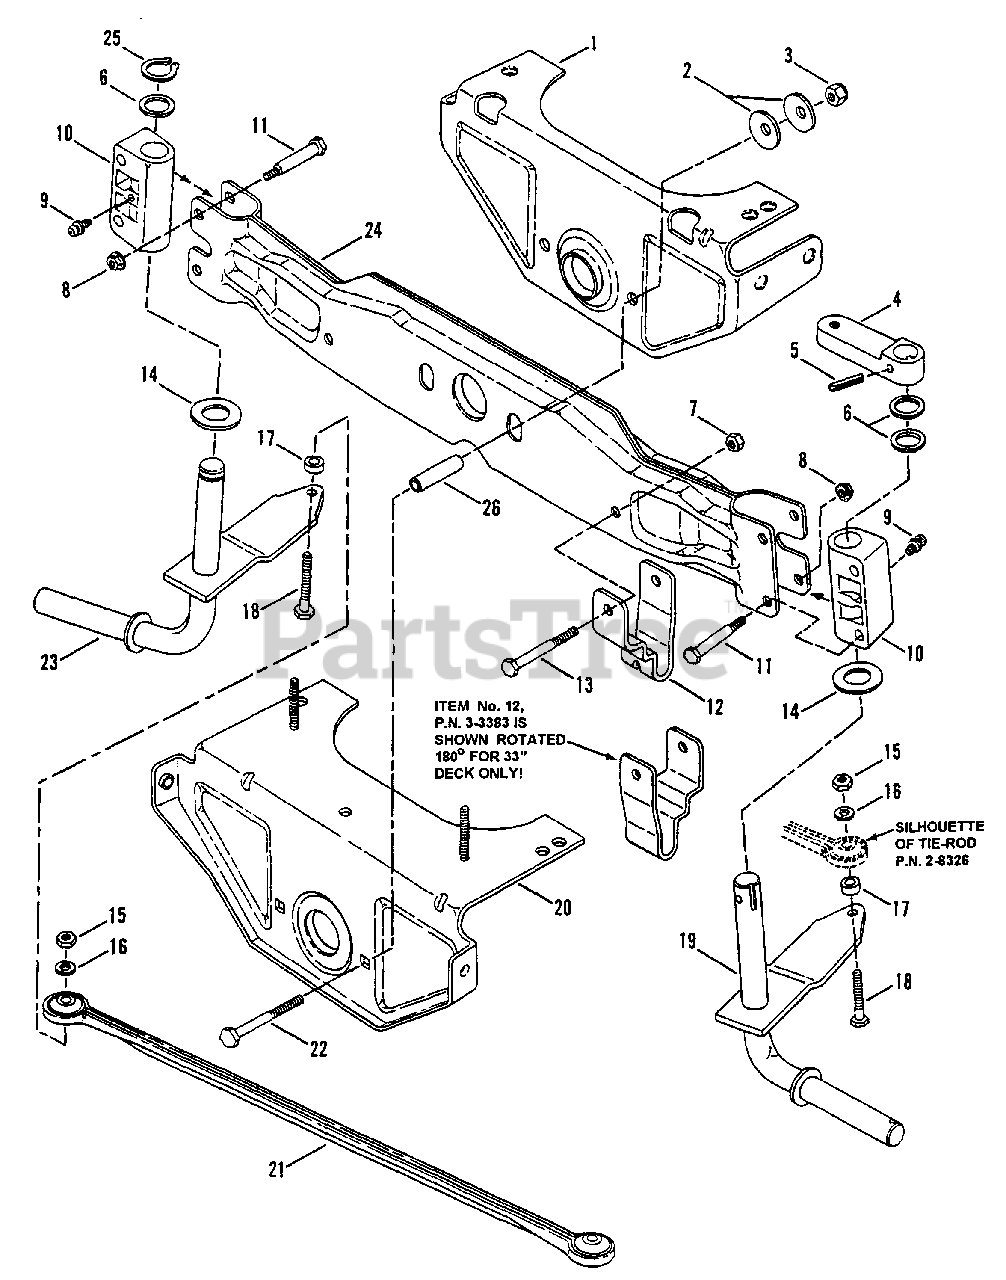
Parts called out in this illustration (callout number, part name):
1	BRACKET, Axle (Rear)
2	WASHER, Cone
3	NUT, 3/8-16 Nyloc
4	ARM, Steering
5	ROLL-PIN, 1/4 x 1-1/4"
6	WASHER, Shim
7	NUT, 5/18-18 Center Lock
8	NUT, 1/4-20 Hex Flg. Top-Lock
9	LUBE FITTING, Straight (press-fit for .187 dia. Hole)
10	BEARING, Spindle
11	BOLT, 1/4-20 x 1-41/64" Shoulder
12	BRACKET, Deck Hanger
13	SCREW, 5/16-18 x 2-1/2" Hex Head Cap
14	WASHER, Thrust
15	NUT, 3/8-16 Hex, Grade 5
16	WASHER, 3/8 Split Lock
17	SPACER, Tie-Rod
18	SCREW, 3/8-16 x 1-1/2" Hex Head Cap, Grade 5
19	SPINDLE ASSY., Left Hand, Long
19	SPINDLE ASSY., Left Hand, Short
20	BRACKET ASSEMBLY, Axle (Front)
21	TIE-ROD
22	BOLT, 3/8-16 x 3 Hex Head
23	SPINDLE ASSY., Right Hand, Long
23	SPINDLE ASSY., Right Hand, Short
24	AXLE, Front
25	RING, Retaining
26	SPACER
